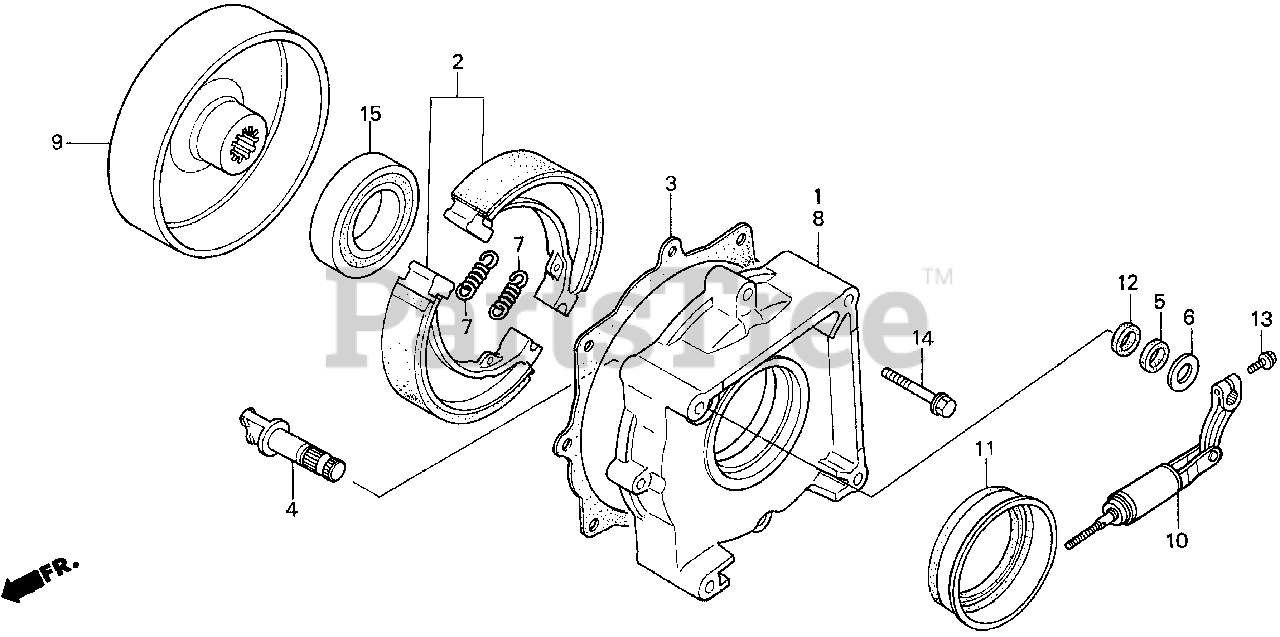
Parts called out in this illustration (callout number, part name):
1	PANEL, R. BRAKE
2	SHOE KIT, BRAKE
3	GASKET, BRAKE PANEL
4	CAM, BRAKE
5	DUST SEAL, BRAKE CAM
6	WASHER, BRAKE CAM
7	SPRING, RR. BRAKE SHOE
8	PANEL, L. BRAKE
9	DRUM, BRAKE
10	ARM, BRAKE
11	DUST SEAL (37X58X9)
12	DUST SEAL (17X23X3)
13	BOLT, FLANGE (8X25)
14	BOLT, FLANGE (8X40)
15	BEARING, RADIAL BALL (6007)
